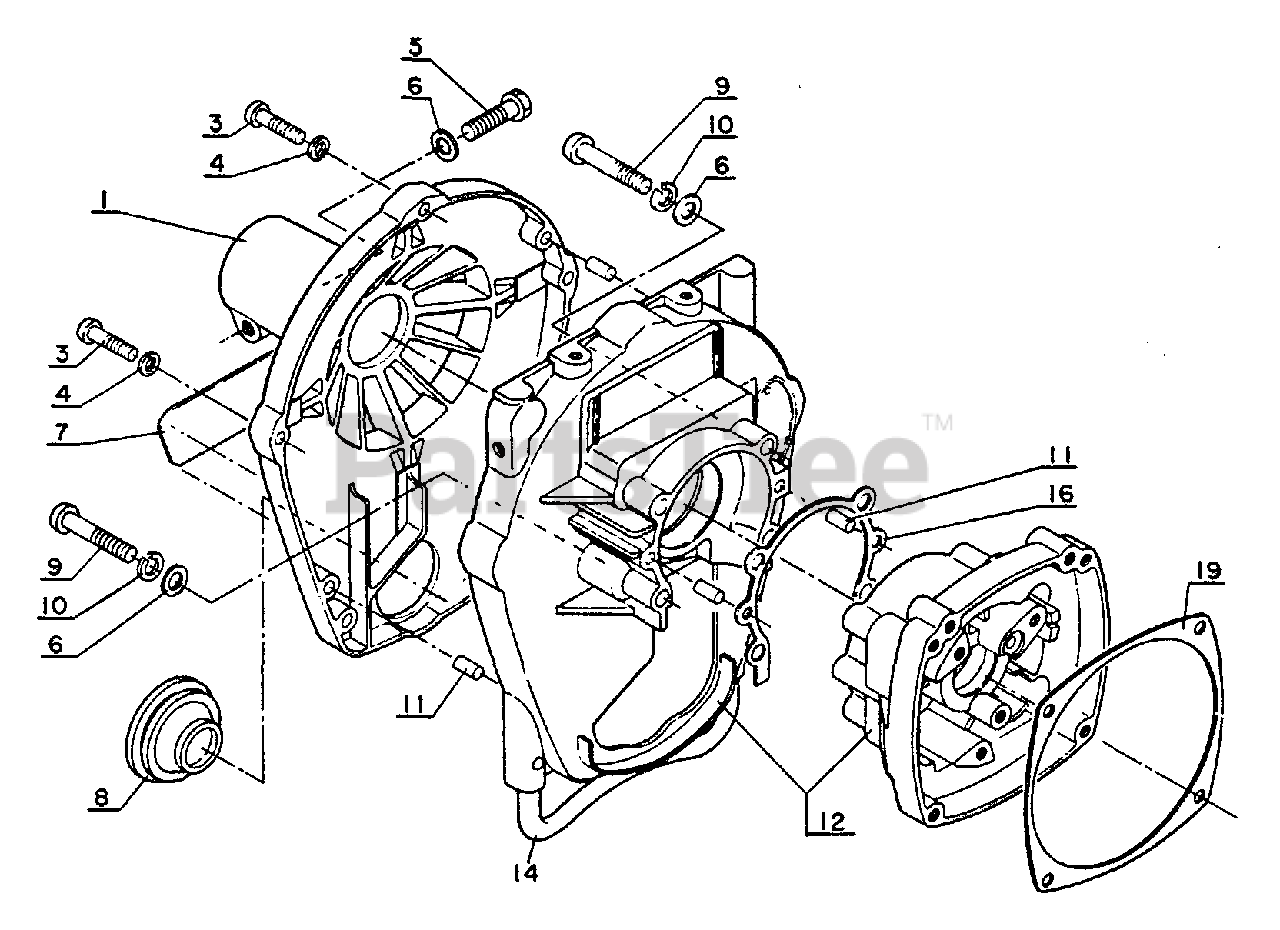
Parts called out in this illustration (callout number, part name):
1	CASE, FAN
3	SCREW - 4X18
4	WASHER - 4
5	BOLT - 5X20
6	WASHER - 5
7	PLATE, MODEL
8	SEAL, DUST
9	SCREW - 5X30
10	LOCKWASHER - 5
11	PIN - LOCATING
12	CRANKCASE KIT
14	STAND
16	GASKET, CRANKCASE
19	GASKET, STARTER
